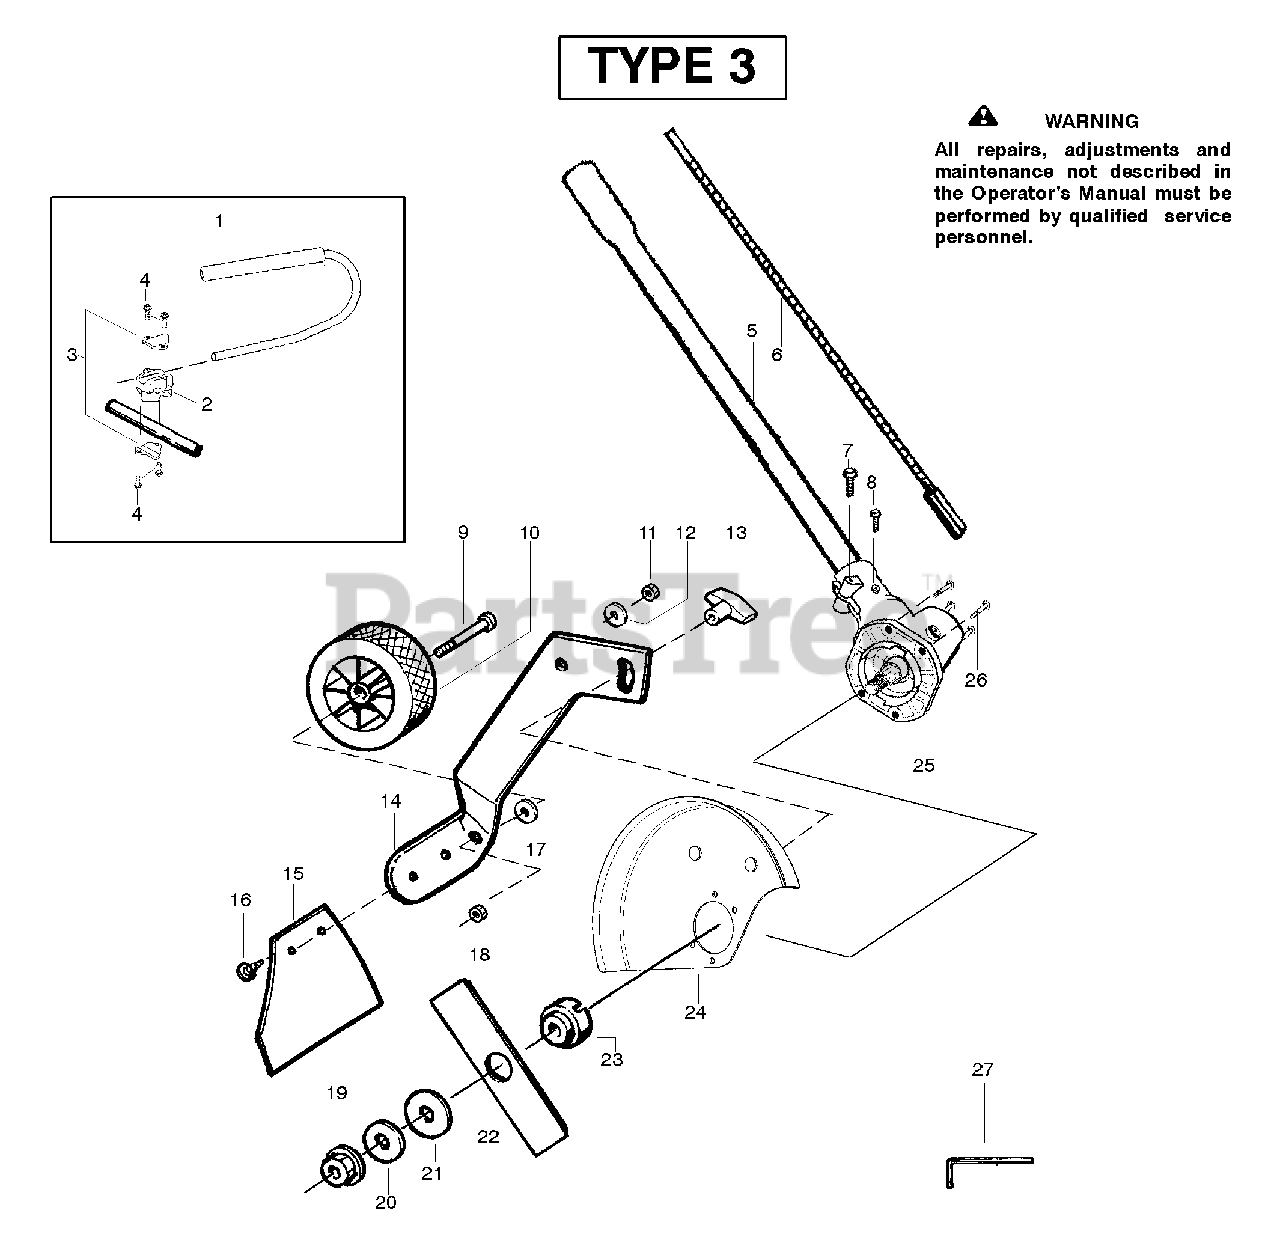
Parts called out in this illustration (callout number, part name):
1	Kit-Handlebar
2	Clamp-Handlebar (7/8")
2	Clamp-Handlebar ( 1")
3	Bracket-Clamp
5	Assy.-Driveshaft
6	Flexshaft-Split boom
8	Screw-Alignment
9	Bolt-Shoulder Axle
10	Wheel-4"
14	Bracket-Adj. Wheel
15	Kit-Mud Flap
16	Fastener-Mud Flap
19	Nut-Flange
20	Washer-Belleville
21	Washer-Flat
22	Accy-7.5" Blade
24	Kit-Edger Guard
25	Kit-Gearbox
27	Wrench-Hex (5/32")
